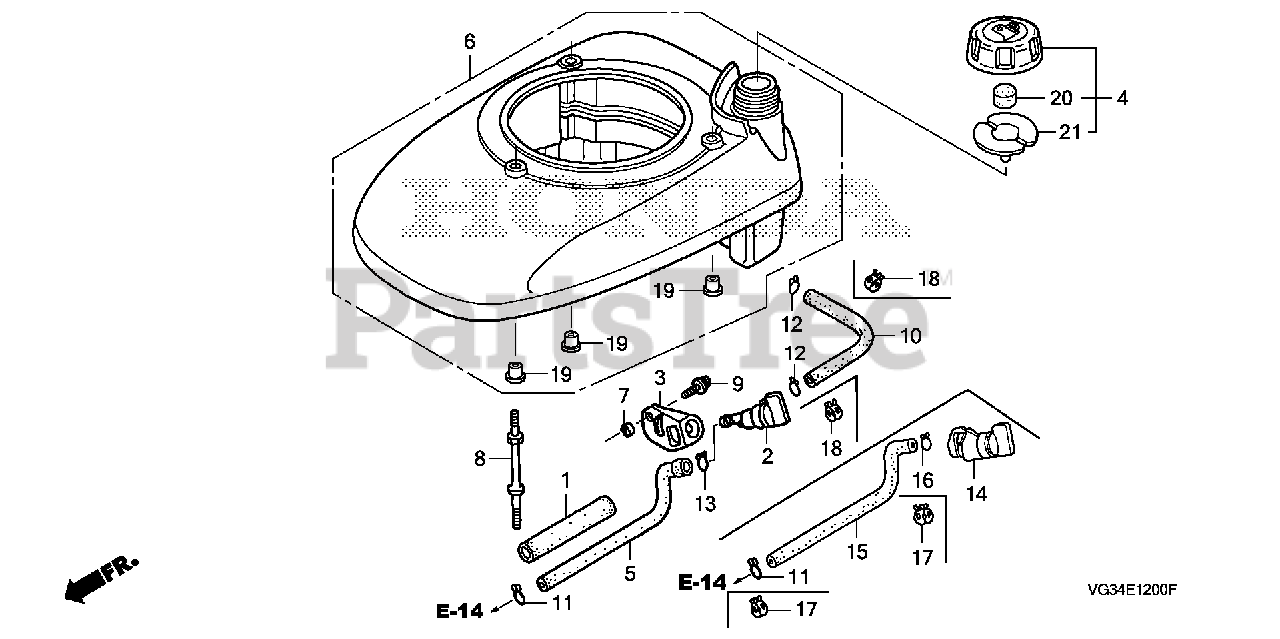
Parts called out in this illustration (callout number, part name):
1	RUBBER, SUPPORTER (107MM)
2	PETCOCK ASSY.
3	BRACKET, PETCOCK
4	CAP ASSY., FUEL TANK
5	TUBE, FUEL
6	COVER KIT, FAN
6	COVER, FAN *R280* (POWER RED)
7	COLLAR, FR. TURN SIGNAL
8	BOLT, STUD (H=42.5MM)
9	SCREW-WASHER (5X10)
10	BULK HOSE, FUEL (5.5X3000) (5.3X150)
11	CLIP, TUBE (B8)
12	CLIP, TUBE (B10)
13	CLIP, TUBE (C9)
19	COLLAR, FAN COVER
20	SPONGE, FUEL CAP BREATHER
21	GASKET, FUEL CAP
